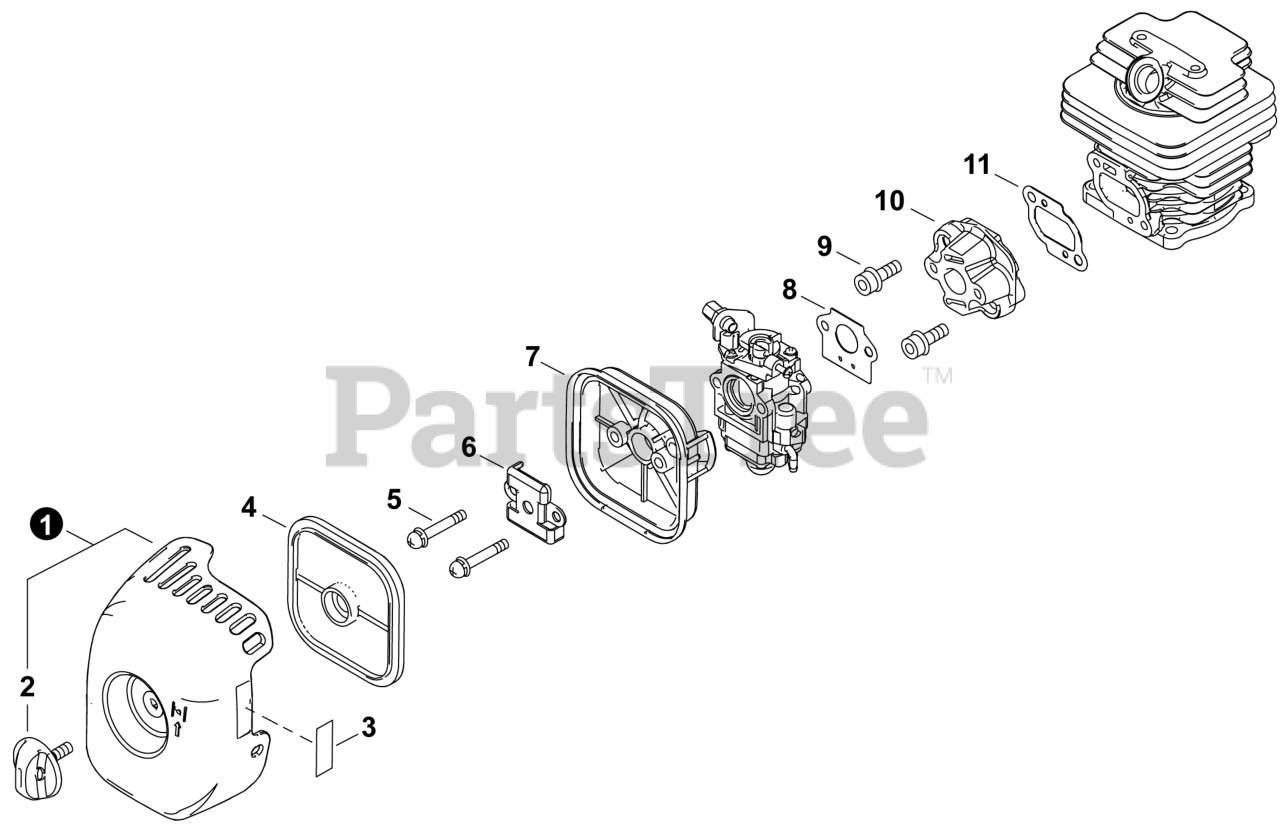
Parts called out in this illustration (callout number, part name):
1	COVER ASSY, AIR FILTER
2	THUMBSCREW
3	LABEL - CHOKE
4	FILTER, AIR
5	SCREW 5x64
6	PLATE, PREVENT
7	CASE ASSY, AIR FILTER
8	GASKET, INTAKE
9	BOLT 5x25
10	INSULATOR, INTAKE
11	GASKET, INTAKE
